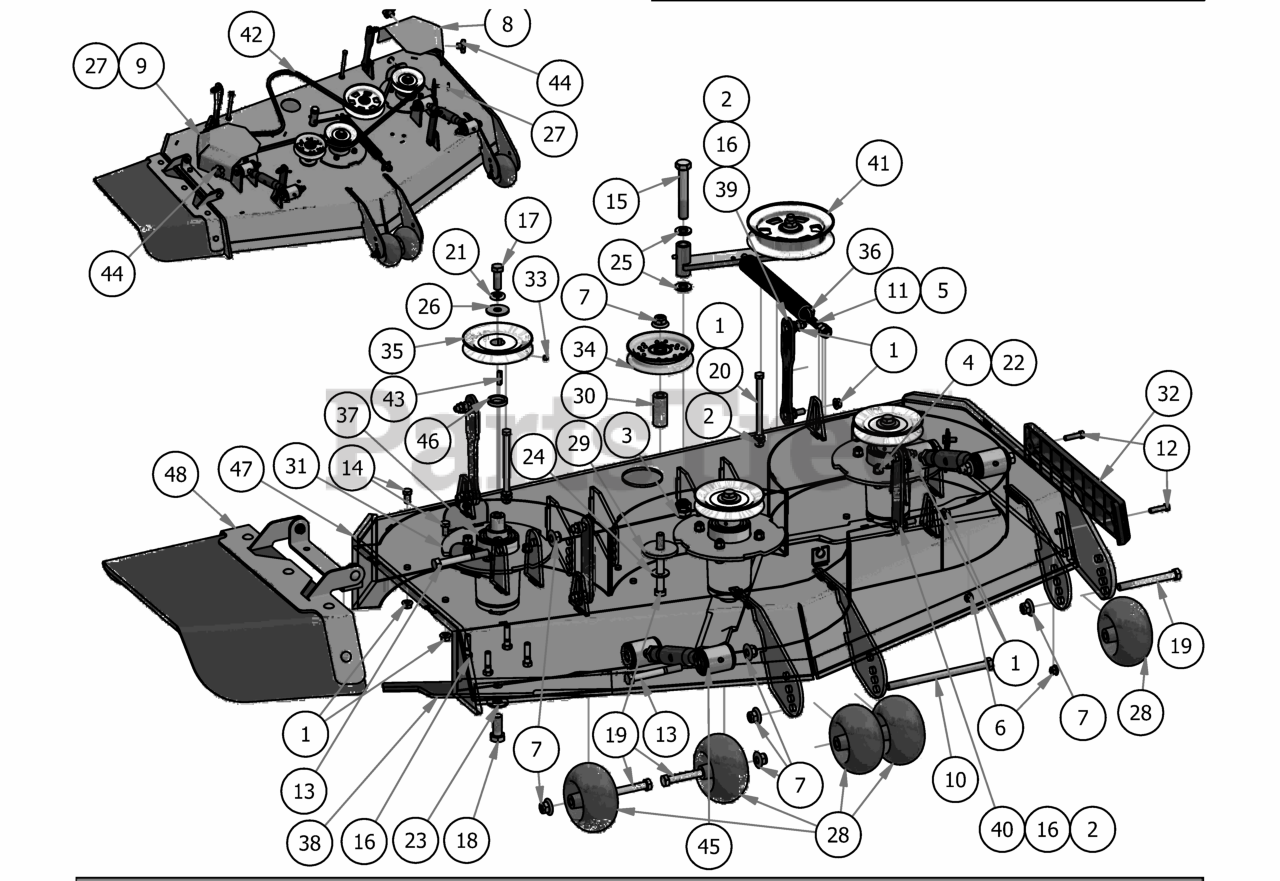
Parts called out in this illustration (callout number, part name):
1	3/8" Flange Nut
2	3/8" Nylock Flange Nut
3	5/8-11 Nylon Insert Jam Half Nut
4	3/8" Hex Nut
5	1/2" Hex Nut
6	5/16" Nylon Flange Nut
7	1/2-13 Nylon Flange Nut
8	2019 Stand On 48" Pulley Cover Trim
9	2019 Stand On 48" Pulley Cover Discharge
10	1/2-13 x 8 Hex Bolt Grade 5
11	All Thread-Pump Idler Tensioner
12	5/16 x 1 1/4 Hex Bolt
13	1/2" x 4" Bolt (Grade 8)
14	3/8" x 3/4" Hex Bolt
15	5/8" x 4" Hex Bolt
16	3/8" x 1 1/2" Hex Bolt
17	1/2"-20 x 1 1/2 - Grade 5 Fine Thread Bolt
18	5/8 x 1 1/2 Grade 8 Hex Bolt (Fine)
19	1/2" x 4 1/2" Bolt
20	3/8-16 x 5 1/2 Hex Bolt
21	1/2" Lock Washer Zinc
22	3/8" Lock Washer
23	5/8'' Flat Washer
24	1/2" Washer (Grade 8)
25	.630 ID Plastic Washer
26	1/2" Belleville Washer
27	.360 ID Plastic Washer-Black
28	2019 Deck Wheel
29	MZ Deck Idler Spacer
30	Stand On Stationary Idler Spacer
31	Deck Spindle Support Plate
32	REVISED TRIM BUMPER_20180226
33	5/16 Set Screw
34	4 3/4 Idler Pulley - ABFI-76
35	5" Spindle Deck Pulley
36	2019 Outlaw Gen2 Deck Spring
37	Spindle Assembly
38	16 1/4" Bad Boy Blade
39	2019 Stand-On Rear Deck Hanger
40	2019 Stand on deck hanger_front
41	2019 Revolt Deck Idler Assembly
43	1/4" x 1" Key
44	5/16" Knob
45	Turnbuckle
46	Spacer, 1x1.375x.25
47	2019 48 Stand On Deck Weldment
48	2019 Outlaw Gen2 Chute Assembly
